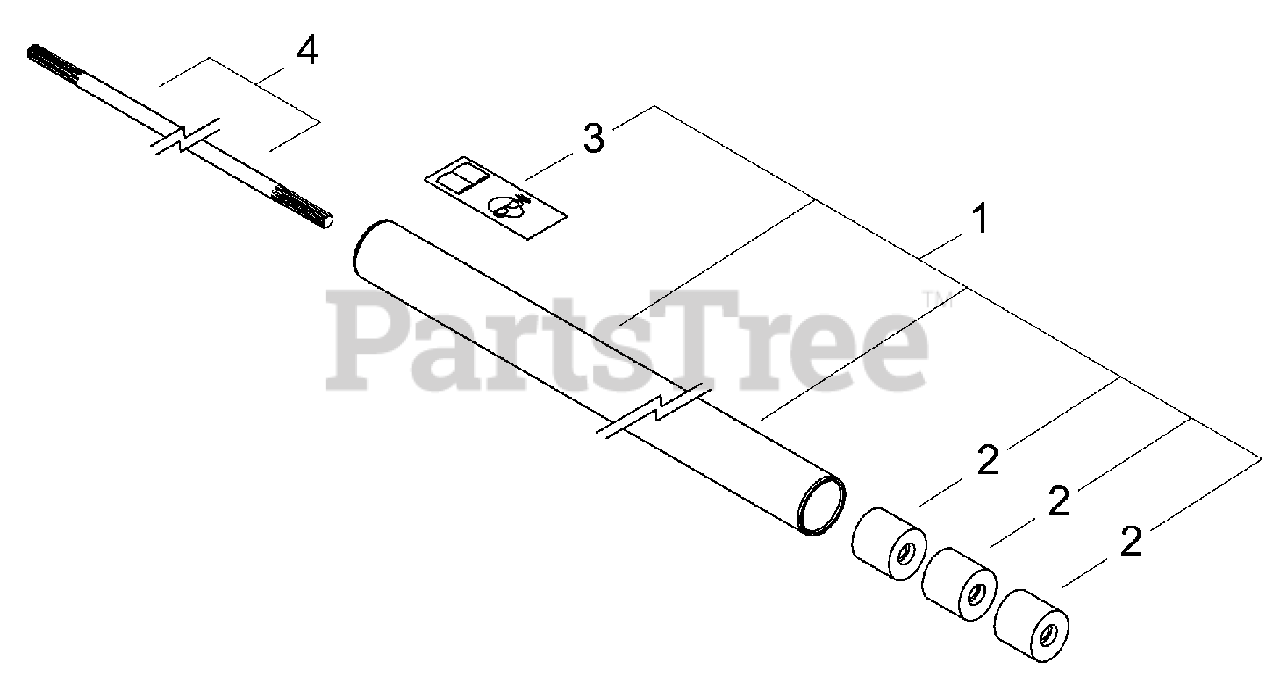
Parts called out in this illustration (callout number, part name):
2	BUSHING
3	LABEL, CAUTION
4	MAINSHAFT Ø6×790 MM
